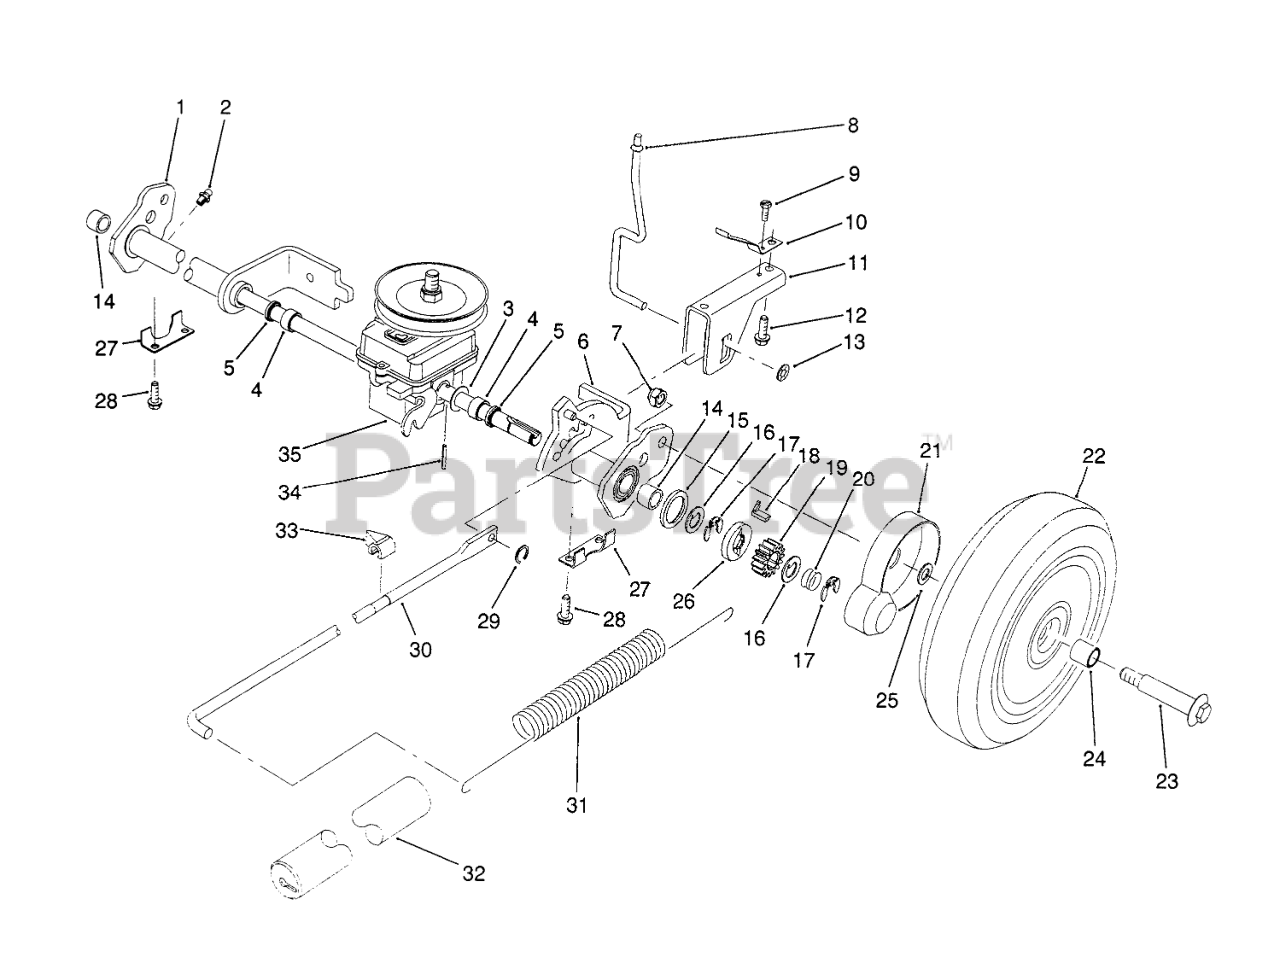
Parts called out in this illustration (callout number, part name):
1	Rear Pivot Assembly R.H. (Incl. Ref. #2, 4, 5 & 14)
2	FITTING-GREASE
3	WASHER-PLAIN
4	BUSHING
5	SEAL-OIL
6	Rear Pivot Assembly L.H.(Incl. Ref. #2, 4, 5 & 14)
7	Nut
8	TRIGGER ROD
9	SCREW 8 - 32 X 250
10	SPRING - TRIGGER RET
11	SADDLE - HOC
12	SCREW
13	PUSHNUT
14	BEARING-ROLLER
15	RING-FRICTION
16	WASHER-THRUST, KEYED
17	RING-CLIP, LOCKING
18	KEY-ROCKING, LH
19	GEAR-PINION
20	SPRING-COMPRESSION
21	COVER-WHEEL
22	Wheel, Tire & Gear Assy . (Incl. Ref. #24)
23	BOLT-WHEEL
24	BUSHING
25	SPACER-COVER, WHEEL
26	WASHER-CLUTCH
27	REAR SECURING PLATE
28	SCREW-HWHTF
29	GRIP RING
30	LINK ROD
31	SPRING-COUNTERBALANCE
32	COVER-SPRING
33	INDICATOR-HEIGHT OF CUT
34	COIL PIN
35	Gearbox Assembly
